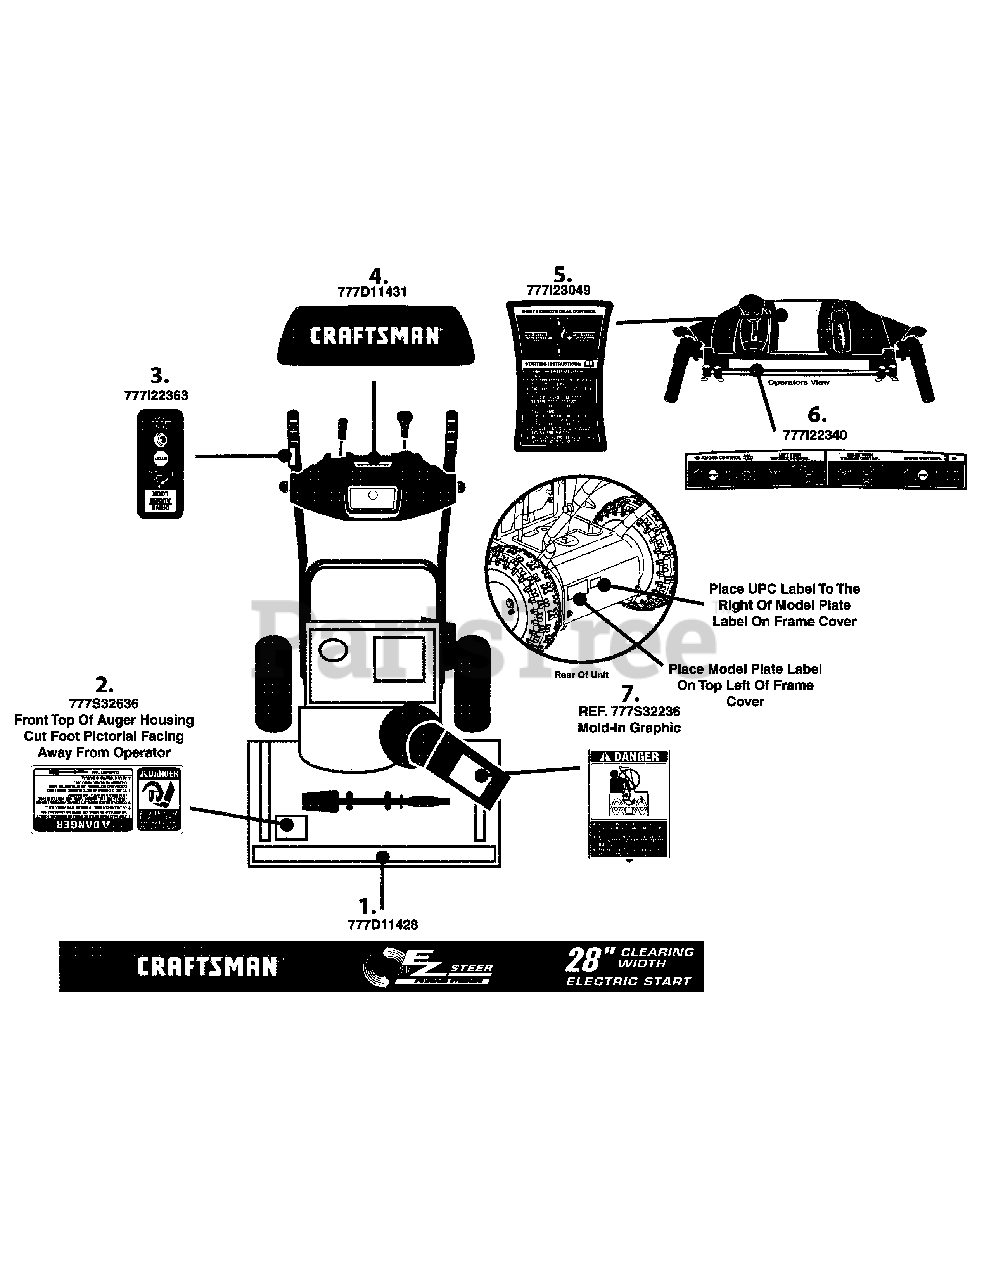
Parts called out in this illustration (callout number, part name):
1	LABEL-SNOW HOUSING CRAFTSMAN 9/28
2	LABEL-SNOW HOUSING
3	LABEL-DRV/AUGR LOCK
4	LABEL-SNOW PANEL CRAFTSMAN
5	LBL-START/CHUTE-4 CNTRL B&S
6	LBL-AUGR/DRV/STEER CNTRL
7	LABEL:SNOW CHUTE
